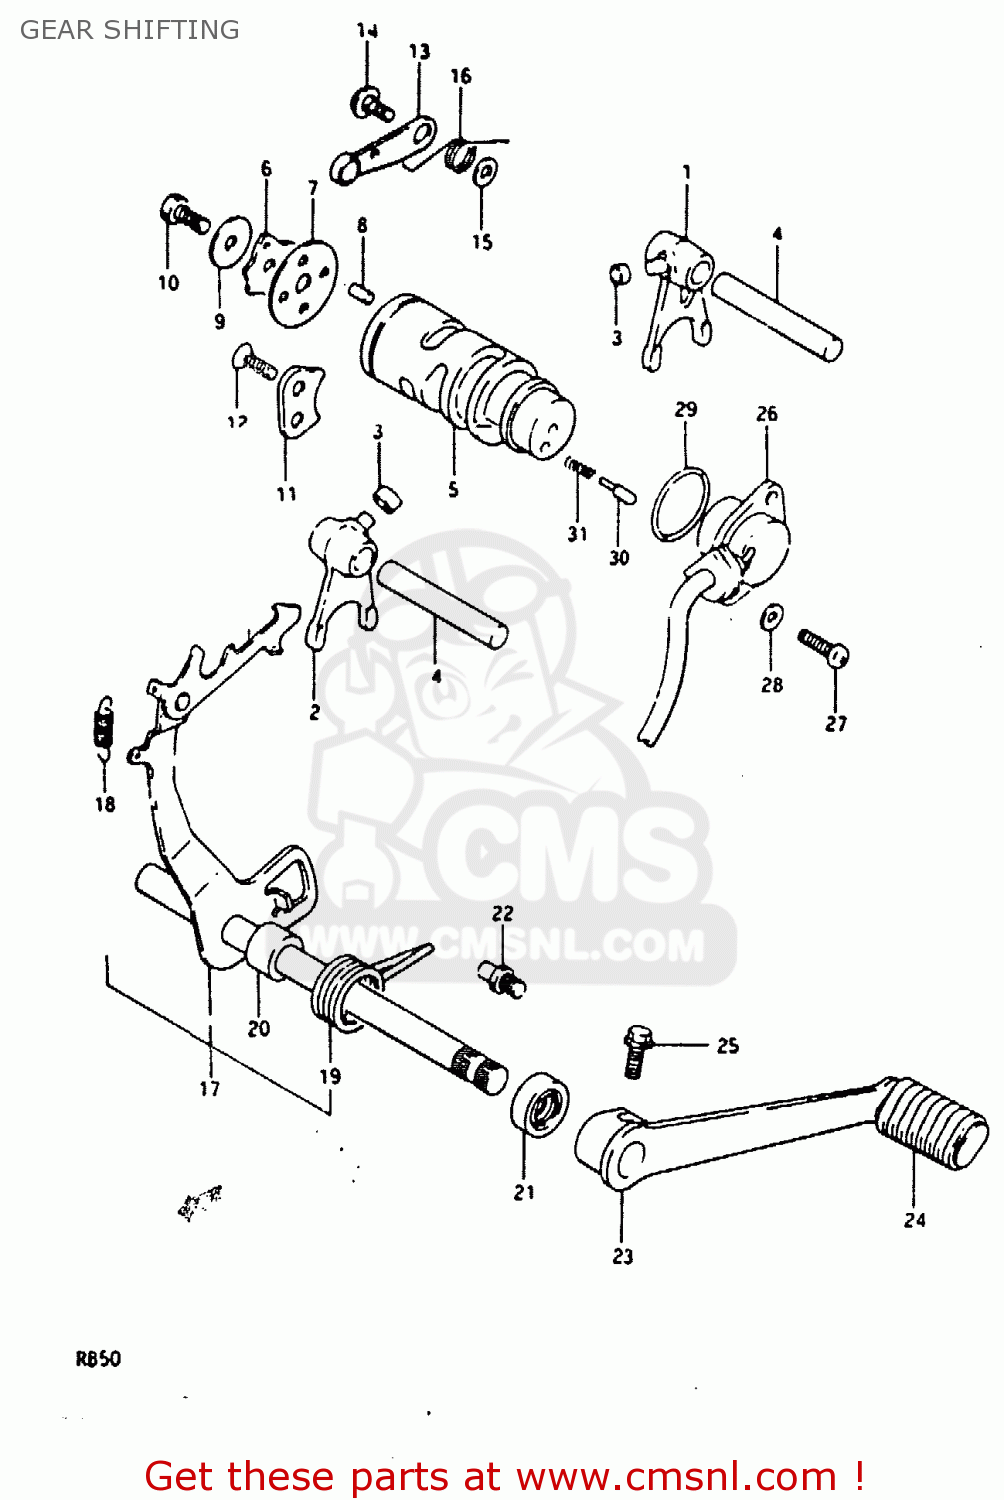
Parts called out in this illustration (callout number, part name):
1	FORK,GEAR SHIFT NO.1
2	FORK,GEAR SHIFT NO.2
3	SPACER(6X9.8X6)
4	SHAFT,GEAR SHIFT FORK
5	CAM,GEAR SHIFT
6	PLATE,GEAR SHIFT CAM STOPPER
7	GUIDE,SHIFT CAM STOPPER PIN
8	ROLLER(4X13.8)
9	WASHER
10	BOLT
11	RETAINER,SHIFT CAM
12	SCREW
13	STOPPER COMP,SHIFT CAM
14	BOLT(6X14.3)
15	WASHER
16	SPRING,SHIFT CAM STOPPER
17	ARM ASSEMBLY,GEAR SHIFT
18	SPRING
19	SPRING
20	SPACER
21	OIL SEAL
22	STOPPER,GEAR SHIFT ARM
23	LEVER,GEAR SHIFT
24	RUBBER,PEDAL
25	BOLT 6X20
26	SWITCH ASSEMBLY,GEAR POSITION
27	SCREW
28	WASHER
29	O-RING (D:2.4 ID:26.2)
30	PIN(5X15.5)
31	SPRING
